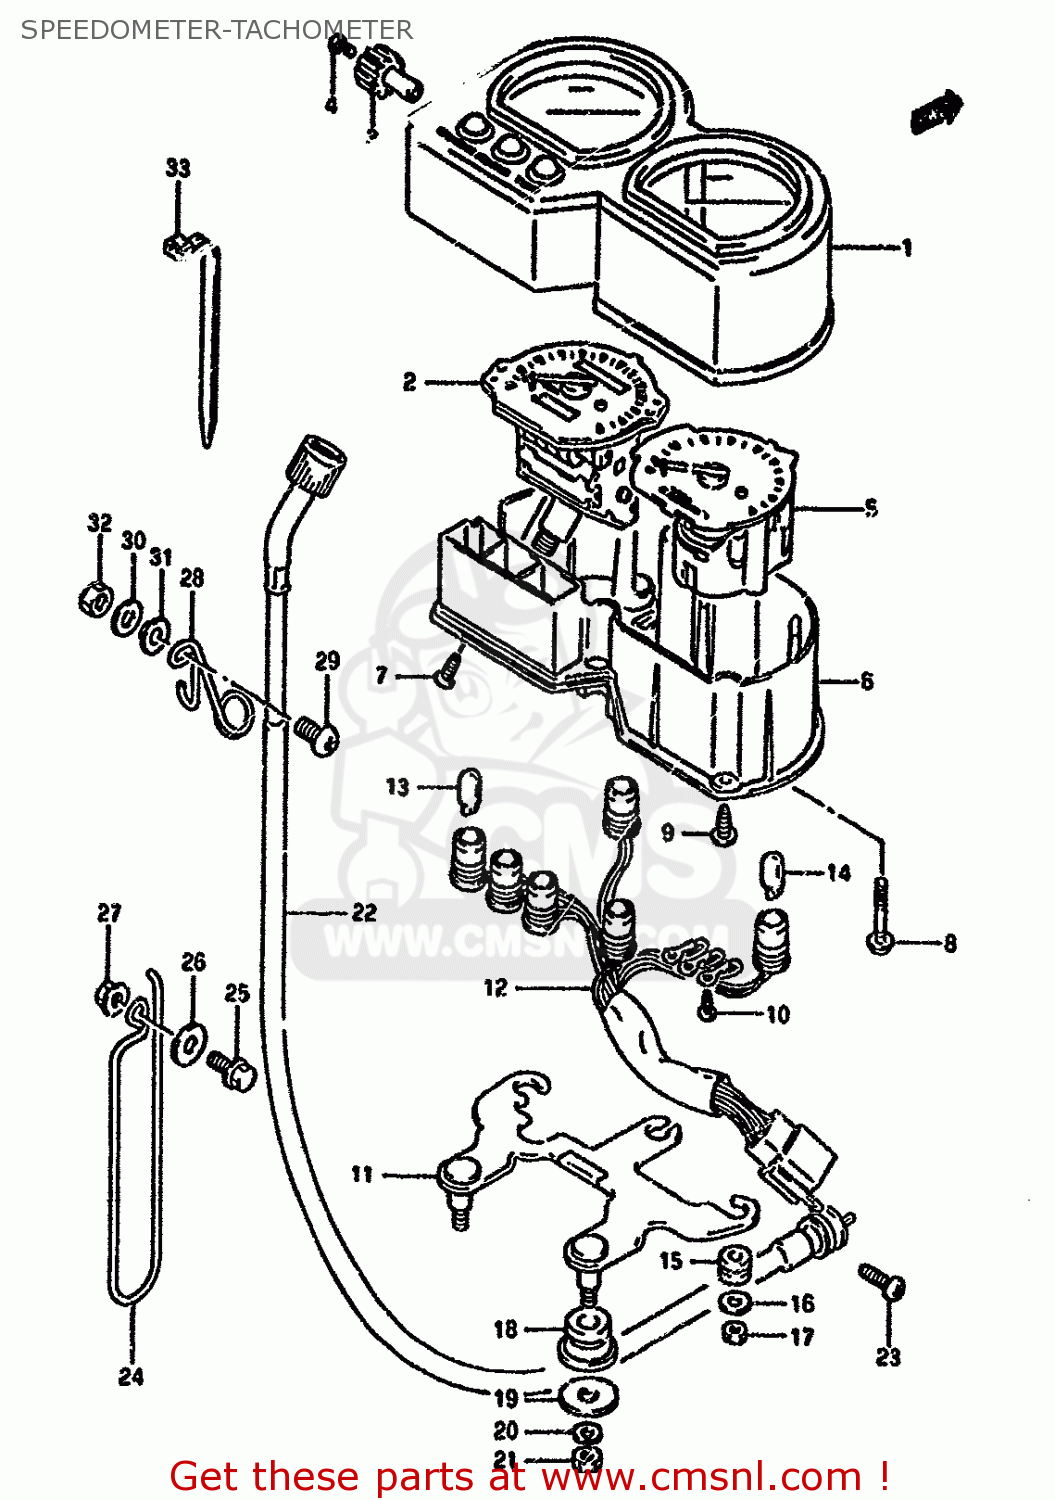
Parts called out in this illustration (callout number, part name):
1	VISOR
2	SPEEDOMETER(KILO)
3	KNOB
4	ROTOR,SPEED
5	TACHOMETER
6	CASE,METER
7	SCREW
8	SCREW
9	SCREW
10	SCREW
11	BRACKET
12	SOCKET,METER
13	BULB(12V3.4W,T10)
14	BULB(12V1.7W,T10,WB121)
15	CUSHION
16	WASHER (5.5X16X1.2)
17	NUT 5MM
18	CUSHION,METER BRACKET
19	WASHER (8.5X20X1.6)
20	LOCK WASHER
21	NUT
22	CABLE ASSY,SPEEDOMETER
23	SCREW
24	GUIDE,METER CABLE NO.2
25	BOLT 6X20
26	WASHER
27	NUT
28	GUIDE,METER CABLE NO.3
29	SCREW
30	WASHER
31	WASHER
32	NUT
33	CLAMP(L:125)
